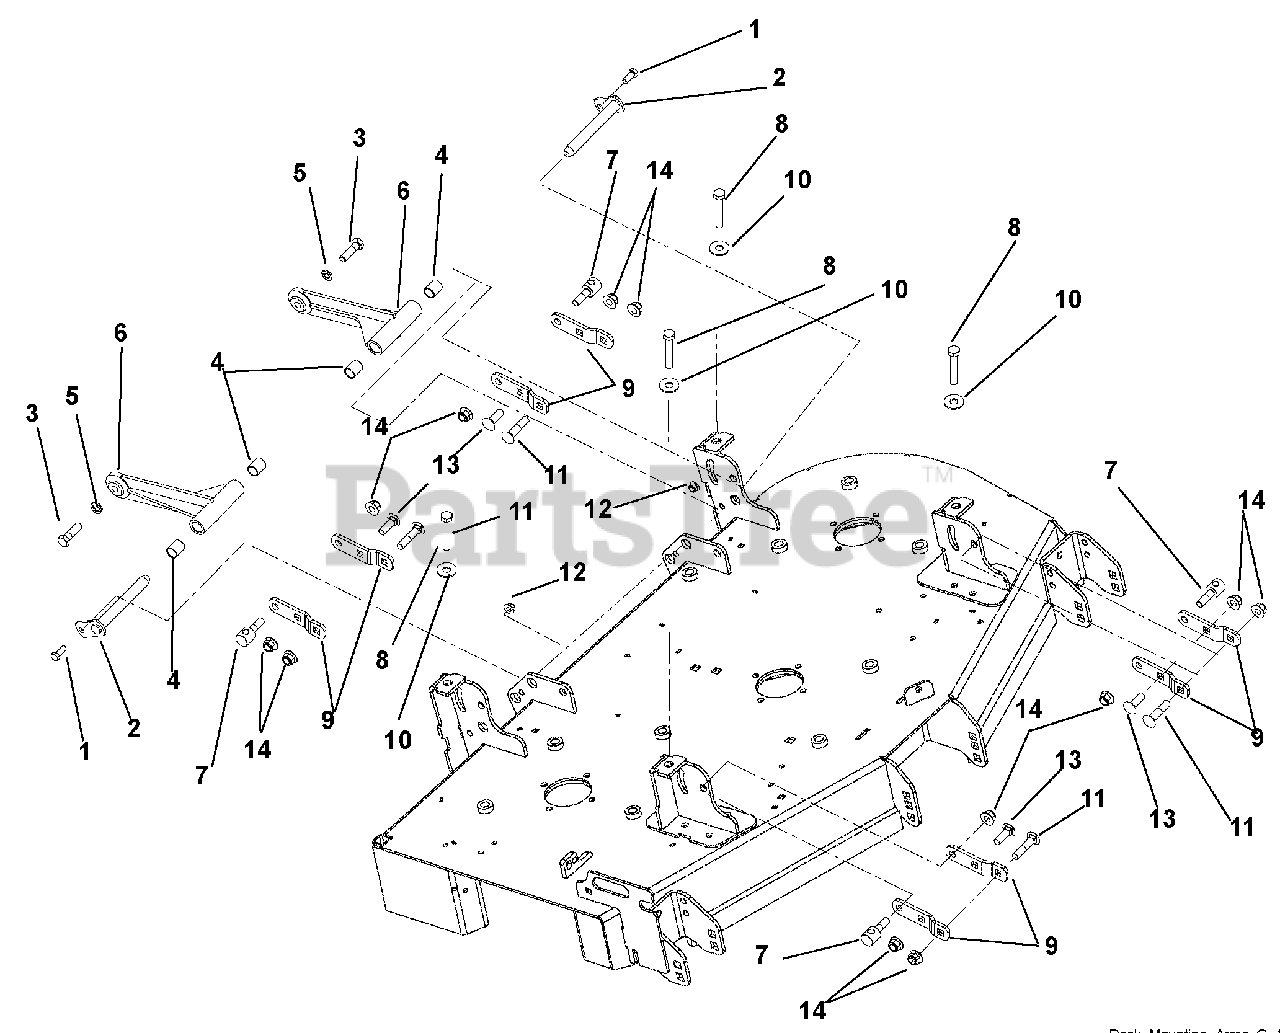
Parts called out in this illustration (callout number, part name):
1	Bolt, Hex .38-16 x 1.00
2	Weldment, Mower Mounting Pin
3	Bolt, Hex .50-13 x 1.75 Grade 5 EP80
4	Bearing, .75 x .875 x 1.00
5	Washer, Locking .50 x .125 Regular
6	Deck Pusher Arm Weldment, Black
7	Trunnion, .50-13
8	Bolt, Hex .50-13 x 3.00
9	Bracket, Deck Leveling
10	Washer, Flat Steel .563 x 1.38 x .109
11	Bolt, Round Head Square Neck .50-13 x 2.25
12	Nut, Locking Nylon Flange .38-16
13	Bolt, Round Head Square Neck .50-13 x 1.50
14	Nut, Locking Nylon Flange .50-13
